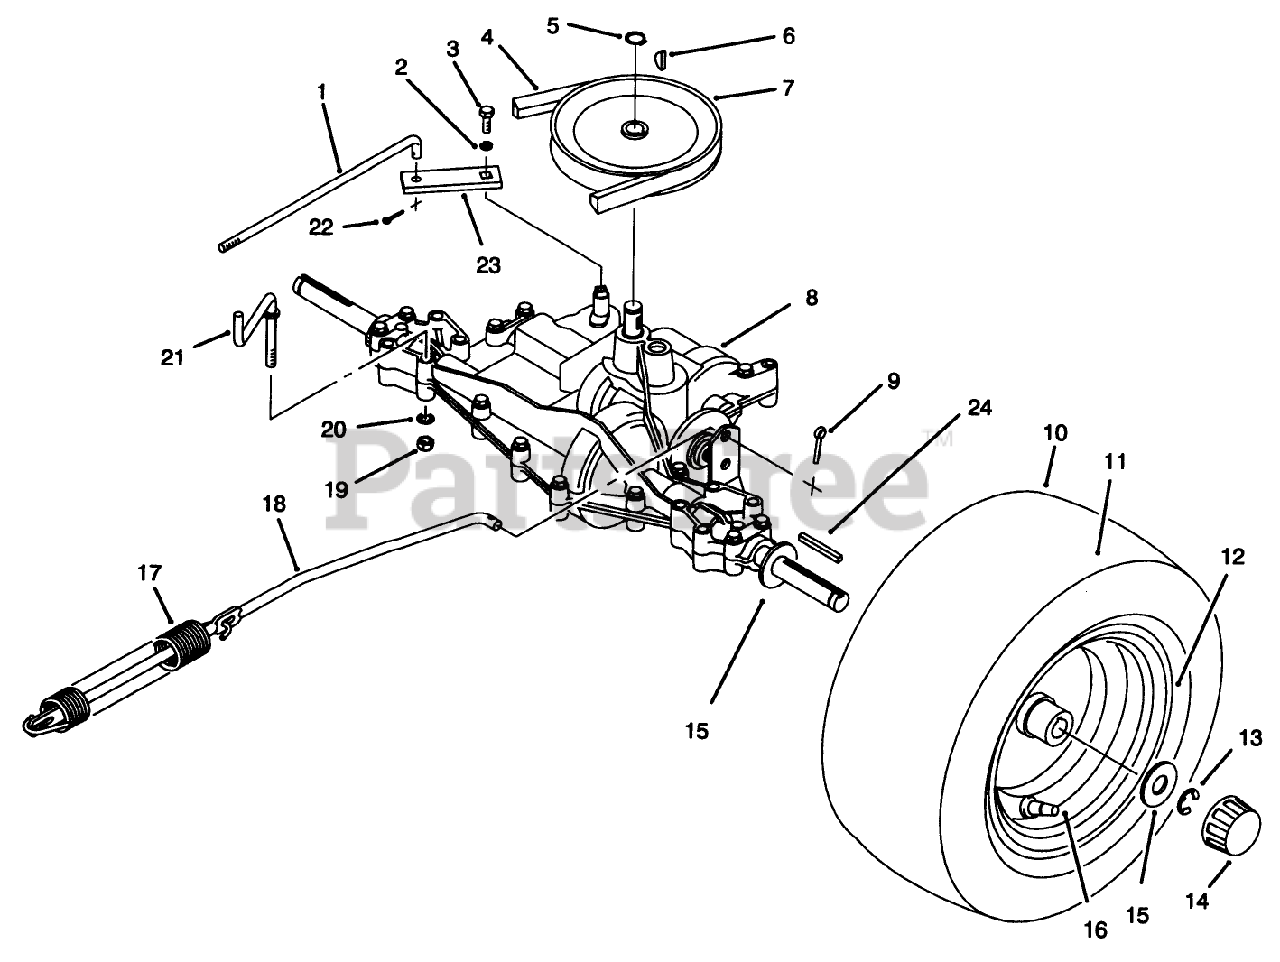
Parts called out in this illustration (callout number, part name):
1	LINK-SHIFT
2	WASHER-LOCK
3	SCREW-HH
4	V-BELT, TRACTION
5	RING-SNAP, EXTERNAL
6	KEY-WOODRUFF
7	PULLEY-TRANSAXLE
9	PIN-COTTER
11	TUBE-INNER
12	REAR WHEEL ASM
13	E-RING
14	CAP-HUB
15	WASHER-PLAIN
17	SPRING-EXT
18	ROD-BRAKE
19	NUT-LOCK, NI
20	WASHER-LOCK, INTERNAL
22	PIN-COTTER
23	LINKAGE
24	KEY-SQUARE
